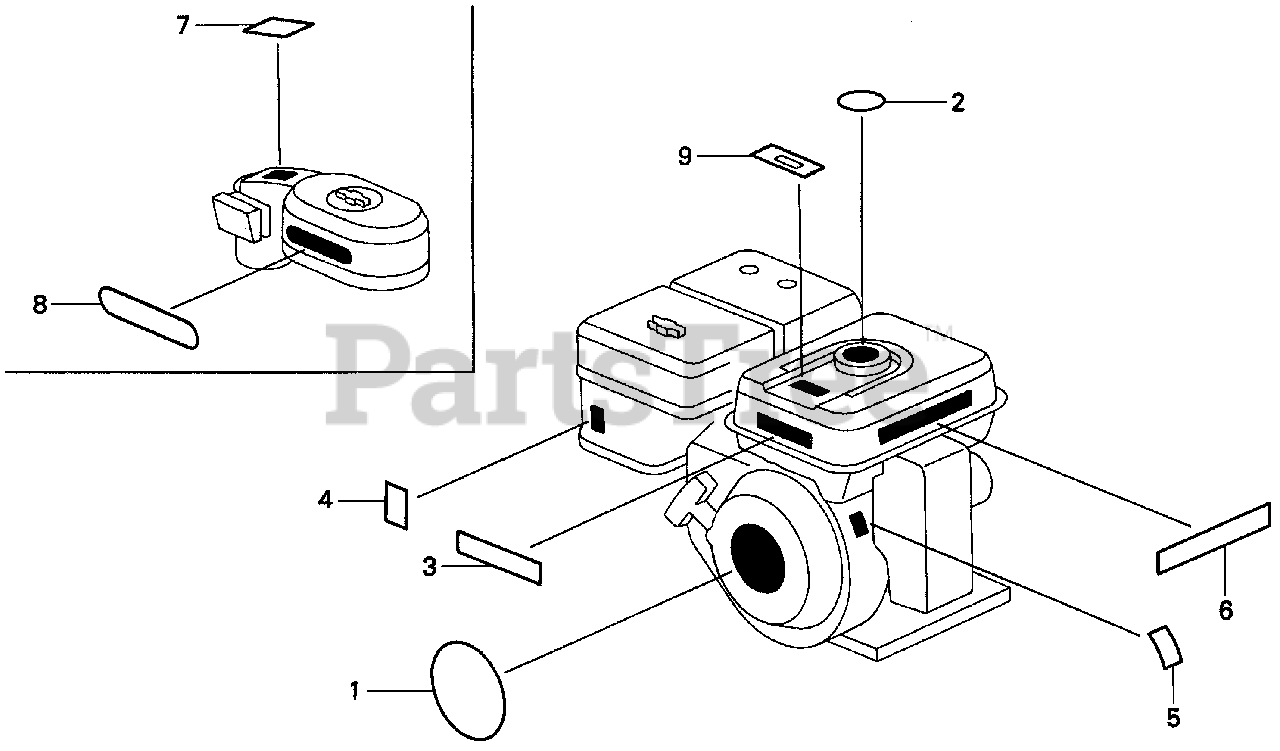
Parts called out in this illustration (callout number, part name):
1	EMBLEM (INTERNAL)
2	MARK, CAUTION (EXTERNAL)
3	LABEL, CAUTION
4	MARK, CHOKE (EXTERNAL)
5	LABEL, SPECIFICATION (EXTERNAL)
6	MARK, OIL ALERT (GERMAN)
6	MARK, OIL ALERT (FRENCH)
6	MARK, OIL ALERT (E)
